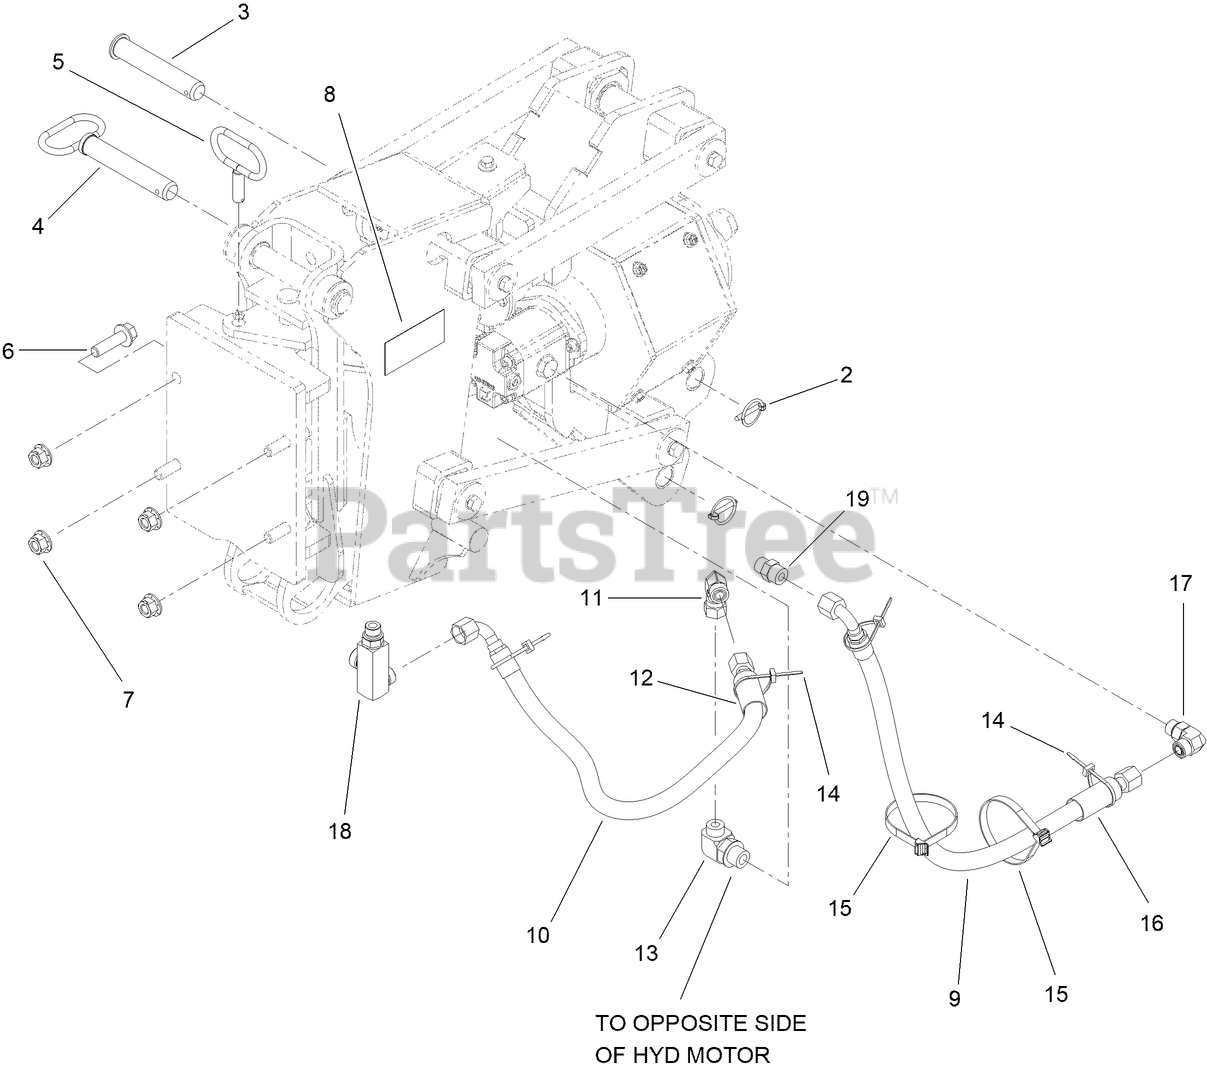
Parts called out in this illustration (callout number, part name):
2	KLIK PIN ASM
3	PIN-MOUNTING, BLADE
5	LOCK-SWING
6	FLG BLT(5/8-NC X 2.25", GR 8)
7	FLG LOCKNUT (5/8-NC, GR G)
8	25542E MAXI SNEAKER PLOW DECAL KIT
9	HOSE (10OFX90S-36"-3000)
10	HOSE (10OFX90S-33"-3000)
11	FITTING-HYD-90
12	ABRASION SLEEVE (1.25" X 33")
13	FITTING-ELBOW 90
14	TIE-CABLE
15	CABLE TIE (1/2") 20" LG
16	ABRASION SLEEVE (1.25" X 37")
17	CONNECTOR (10S-10O90)
18	CONNECTOR (10S-10O-12O)
19	CONNECTOR (10S-10O)
